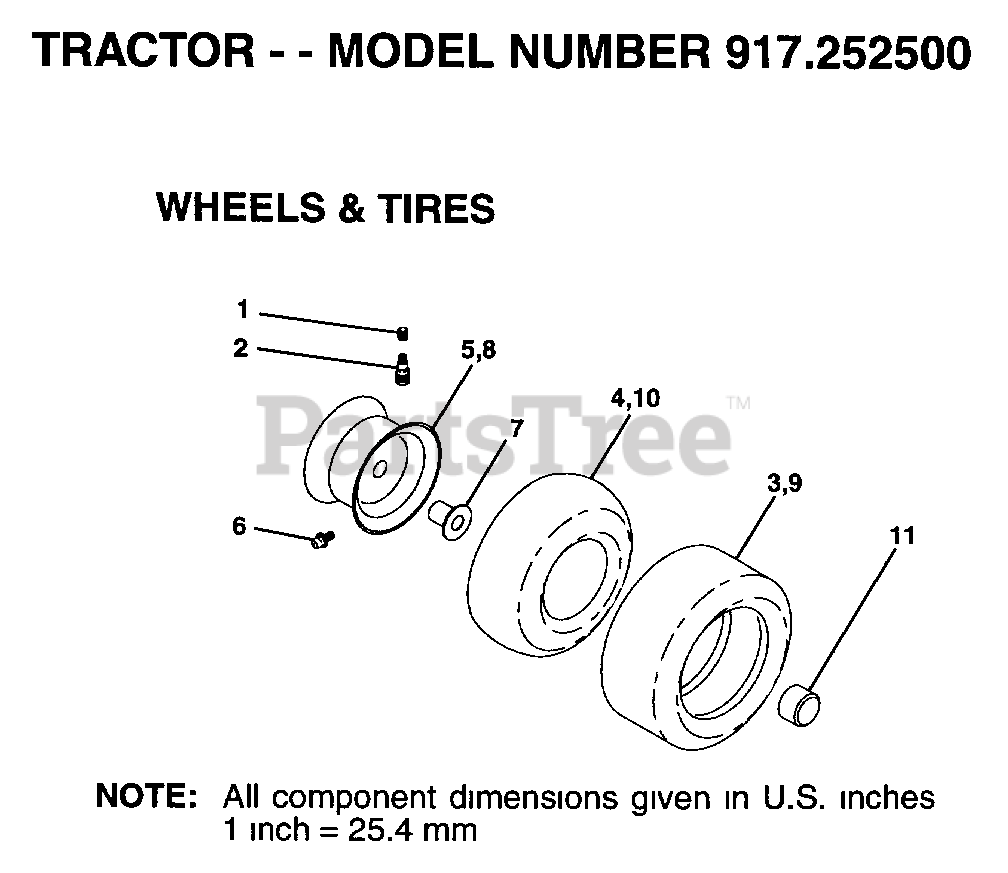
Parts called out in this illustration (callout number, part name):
1	VALVE CAP
2	VALVE STEM LT
4	TUBE.5.3/4.5/6
5	"RIM,FRT T"
6	FITTING LT
7	"FLANGE, BEARING"
8	"RIM 8"""
10	TUBE.18X9.5-8
11	CAP HUB AXLE BLK 1 50X 1 00
